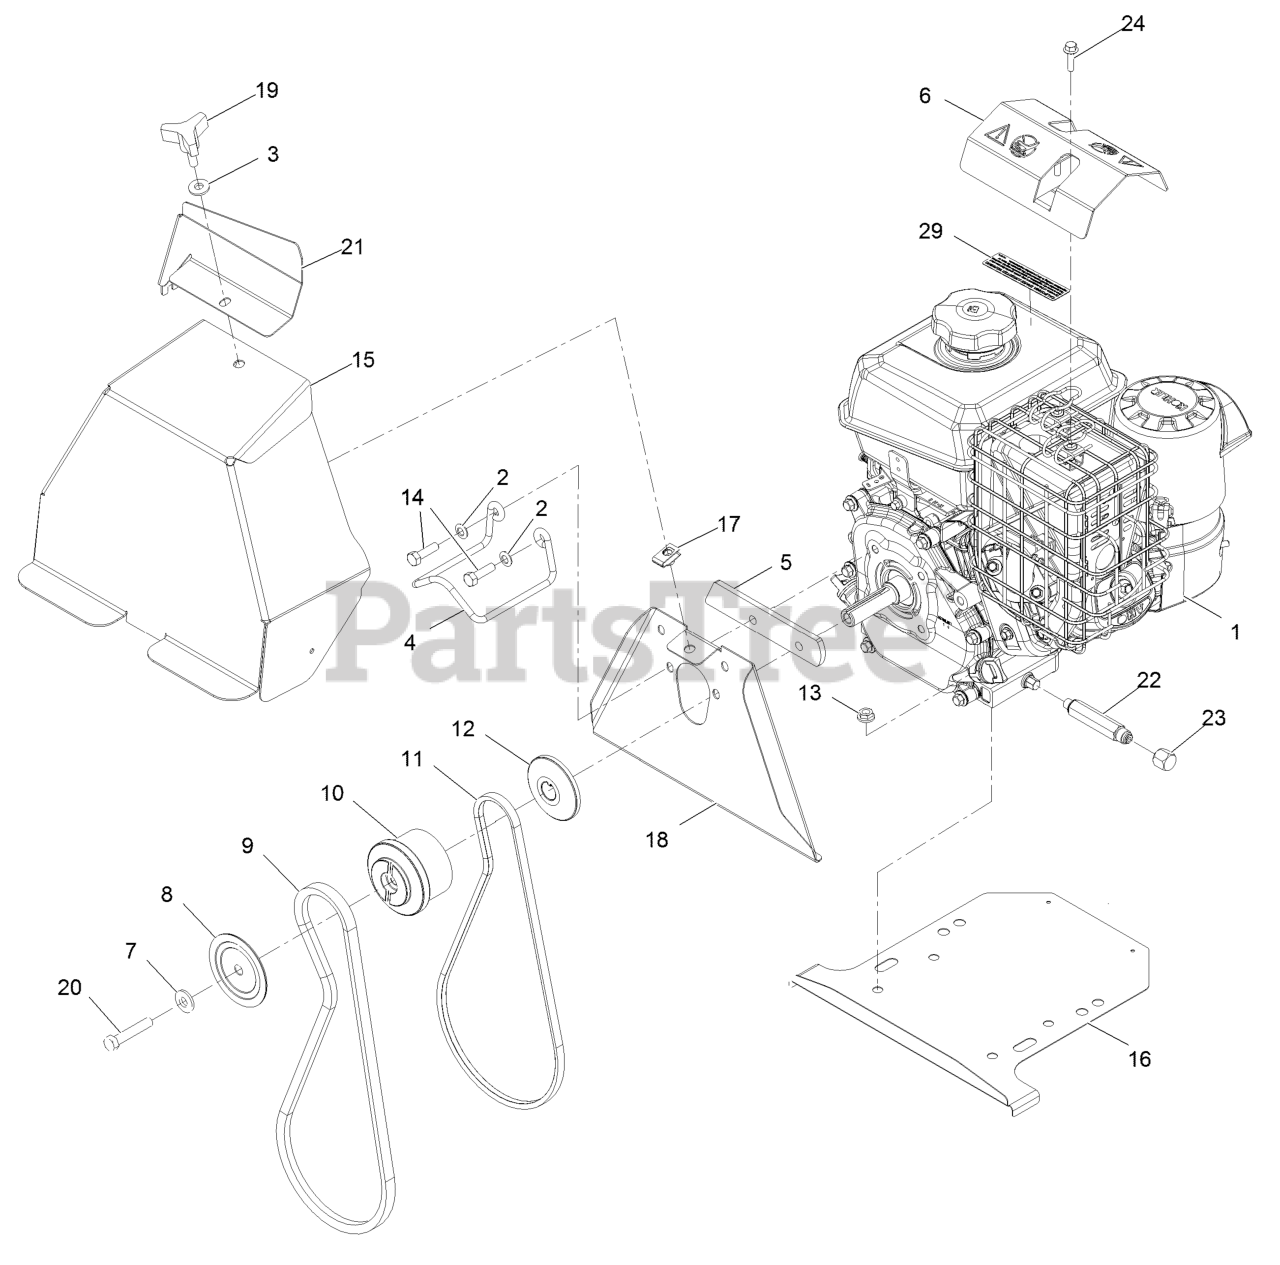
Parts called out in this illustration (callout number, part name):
2	Washer-Belleville
3	Washer-Spring Disc 5/16
4	Guide-Belt
5	Spacer-Cover, Belt
6	Deflector-Debris, Muffler
7	Washer-Spring Disc 3/8
8	Sheave-Half, Impeller
9	Belt
10	Pulley-Engine, Center
11	V Belt-Traction
12	Sheave-Half, Traction
13	Nut-Whizlock 5/16-18
14	Bolt-HH 5/16-24 X 1 1/8
15	Cover - Belt
16	Shield-Drive
18	Cover-Belt, Back
20	Screw-HH
21	Shield-Ice, Kc Ch270
22	Adapter
24	Screw-HHF
29	Decal-Arrester, Spark
